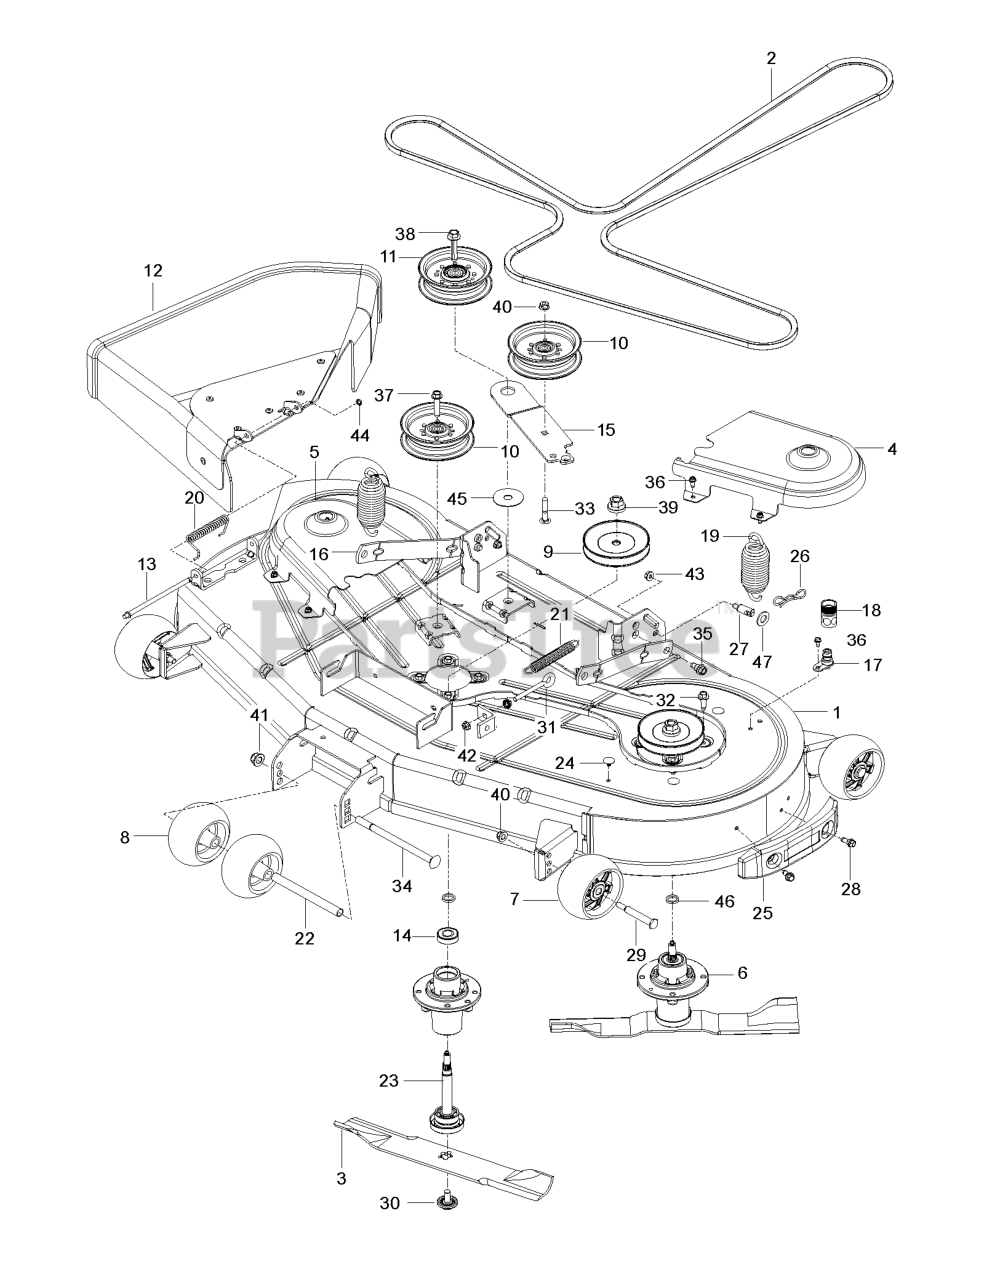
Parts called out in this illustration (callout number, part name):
1	DECK.SVC.54.CLRCT.RZ.MS668
2	BELT.54CC.DRIVE.DECK.RZ.LONG
3	BLADE CC54 PZ STYLE HI LIFT BL
4	COVER.PNT.54CC.MNDRL.LH.ZTR.GY
5	COVER 54 CLEARCUT RH MANDREL G
6	MANDREL ASM, CAST IRON
7	WHEEL.GAUGE.RALLY
8	ROLLER, GAUGE .635 BORN
9	PULLEY.MANDREL.CRD 107CM.DOM.
10	PULLEY.IDLER.2006
11	RB PULLEY.IDLER.4.50/HUB SPEC
12	DEFLECTOR ASSY 54 CLEARCUT RES
13	ROD.HINGE
15	ARM IDLER ARM, CLEARCUT 54 BLA
16	ARM.RFIXED.MOWER.SUSPNSIONX431
17	PORT.WASHOUT
18	COUPLING.QUICK CONNECT
20	SPRING.42.FCS.DEFLECTOR
21	SPRING.EXTN.42.FCS.TR.DECK.DRV
22	TUBE, ROLLER AXLE LONG
23	SHAFT ASM MANDREL
24	PLUG CHRISTMAS TREE
25	BUMPER ASSY 54 CLEARCUT TRIM S
26	PIN.COTTER.7/16.BOW TI.
27	STUD.FASTNER.W/ANTI-ROTATE
28	SHOULDER BOLT 5/16-18TT
29	BOLT.SHOULDER.3/8-16X3-5/8.
30	BOLT.WASHER.ASM.7/16-2
31	EYE BOLT 5/16 X 3.50
32	BOLT.HEX.WASHR.HED.313-18X1.19
34	RHSNB 1/2-13 X 8 GR5 ZD
35	BOLT.SHOULDER
36	SCREW.1/4-20X5/8
37	SCREW LT
38	SCREW.7/16-14 X 2.125.WASHER
39	NUT.FLANGE.LOCK.TOP
40	NUT LOCK FLG 3/8-16 UNC
41	NUT, 1/2-13 HEX FLG NYLOC ZD
42	NUT 5/16C WHIZ
43	NUT LOCK HEX FLANGE 5/16-18
44	NUT PUSH M
46	WASHER.SPACER.MANDREL
47	WASHER.CLEAR.ZINC
